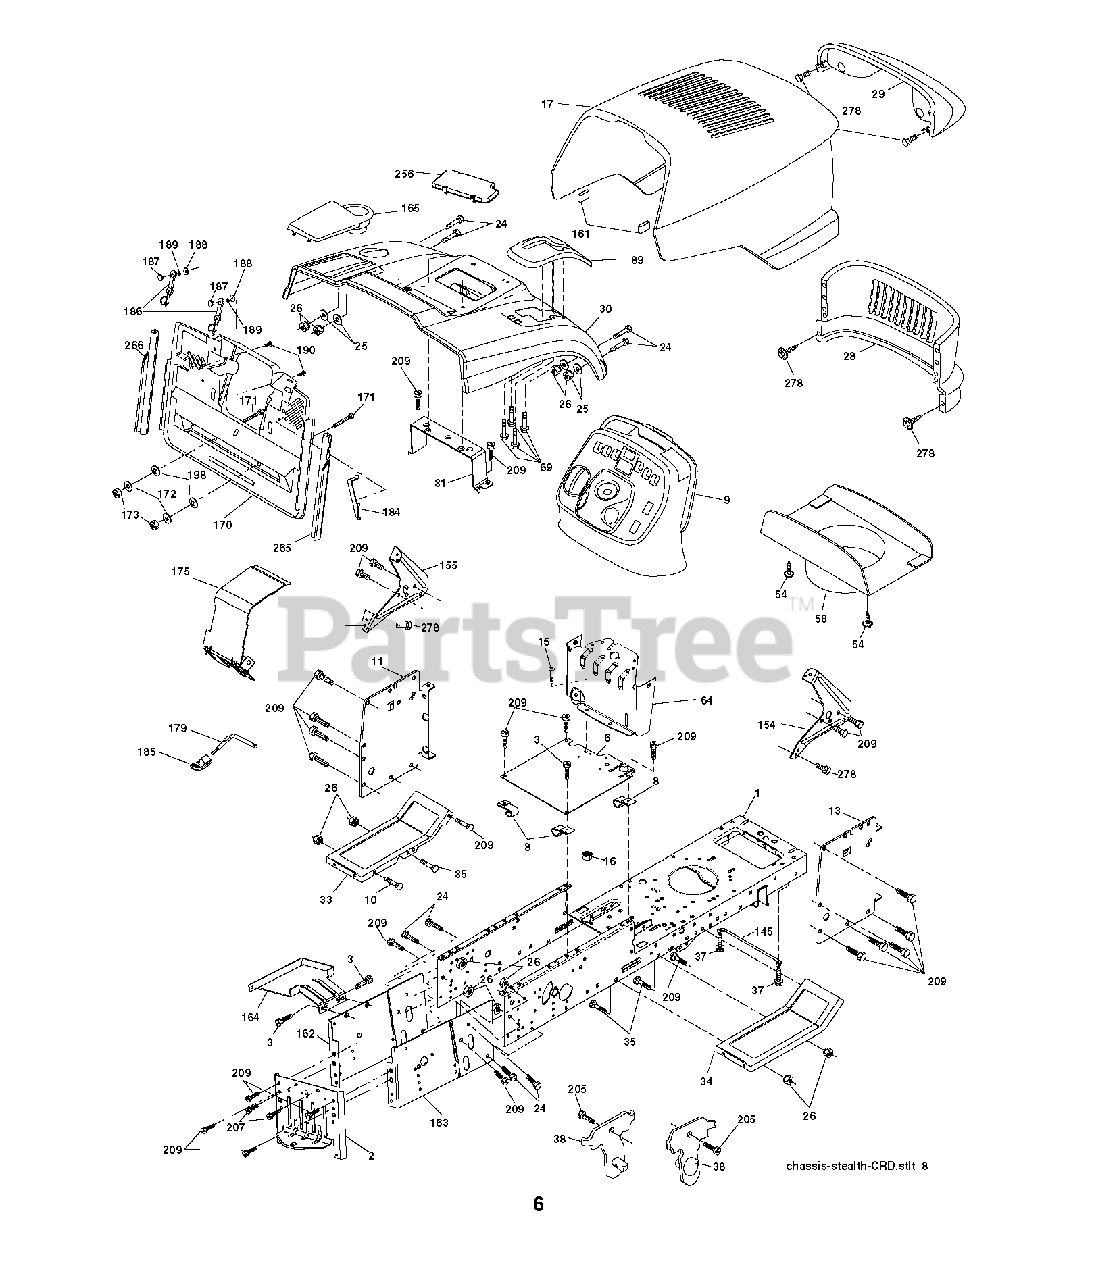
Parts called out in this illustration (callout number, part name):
1	CHASSIS
3	SCREW 3/8-16X3/4
8	CLIP,INSULATOR
10	BOLT D
13	PANEL DASH RH
16	NUT
25	WASHER
26	NUT
31	BRACKET SUPPORT FENDER
54	SCREW.WSHD.HEX10-32X5/8
58	DUCT HOOD
69	SCREW.HI-LO.CONSOLE
145	ROD.PIVOT.HOOD
161	EXTRUSION BUMPER
164	SUPPORT
171	BOLT
172	WASHER
186	LATCH ASSY
187	WELDNUT
189	LOCKWASHER
207	SCREW, 5/16-18 X 1/2
209	SCREW, 3/8-16X3/4
278	SCREW.#10 X 0.750.BOS THREAD
